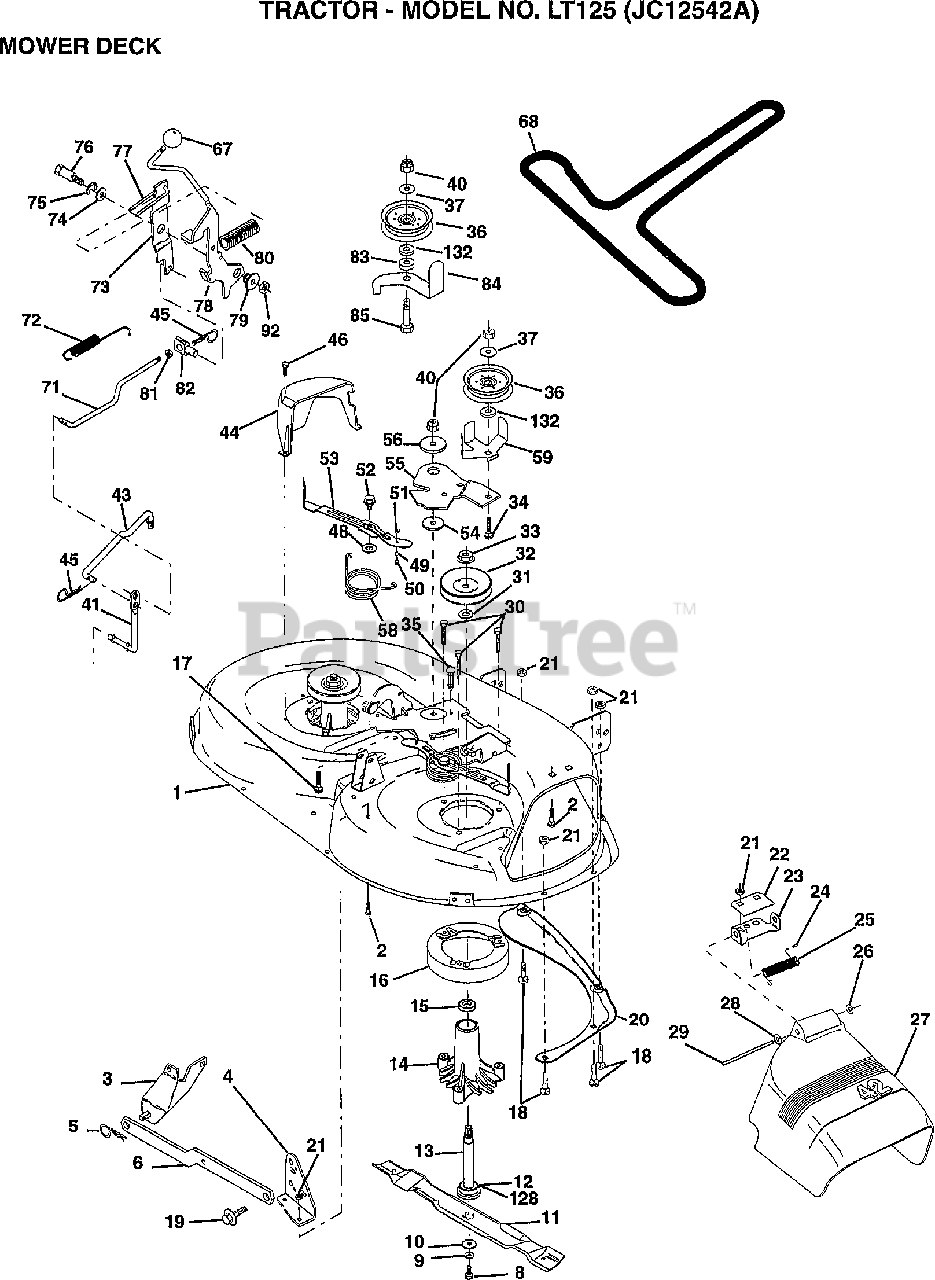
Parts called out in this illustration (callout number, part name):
2	BOLT, CARRIAGE
9	WASHER LOCK HVY 3/8
17	BOLT RDHD SQ NECK 3/8-16 X 1.25
18	BOLT RDHD SQNK 5/16-18 X 5/8
21	LOCKNUT, CROWN 5/16-18
28	WASHER 11/32 X 5/8 X 16 GA
34	BOLT
37	WASHER 13/32 X 13/16 X 16 GA
40	NUT, CROWNLOCK 3/8-16
48	WASHER HARDENED SMALLER
75	RING KLIP #T5304-75
81	NUT HEX JAM 3/8-16 UNC
85	BOLT RDHD SQ 3/8-16 X 2-1/4
92	LOCKNUT
132	WASHER 13/32 X 1-3/8 X GA
